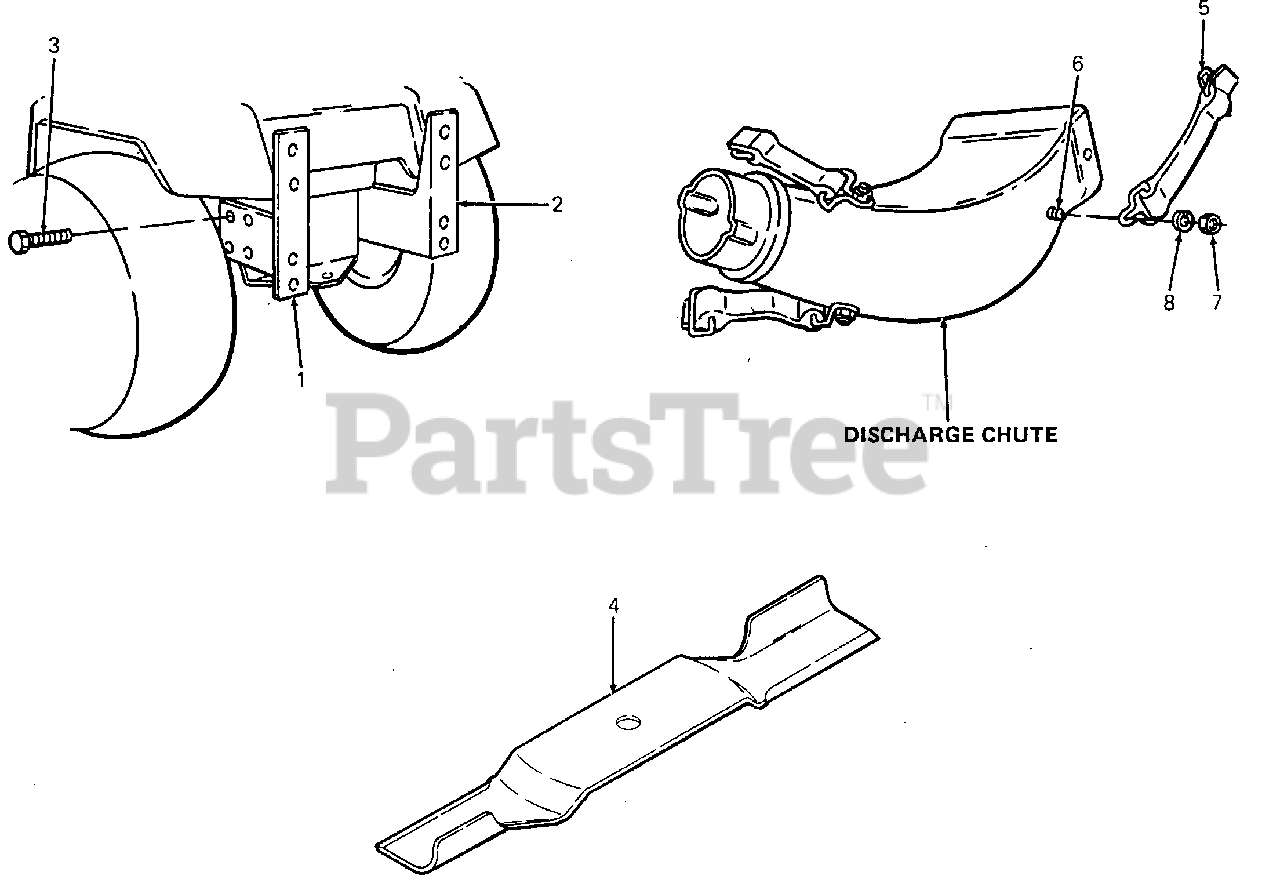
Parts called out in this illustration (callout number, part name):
1	Bracket, LH - Bagger Support
2	Bracket, RH - Bagger Support
3	Screw, Hex Cap, 3/8-16 X 1.0 Lg GR 5
4	Blade, Mower - High Lift
5	Strap Assy, Retainer
6	Screw, Hex Cap, 1/4-20 X .62 Lg
7	Nut, Hex Insert Lock, 1/4-20
8	Washer, Spring, .265 ID X .562 OD
